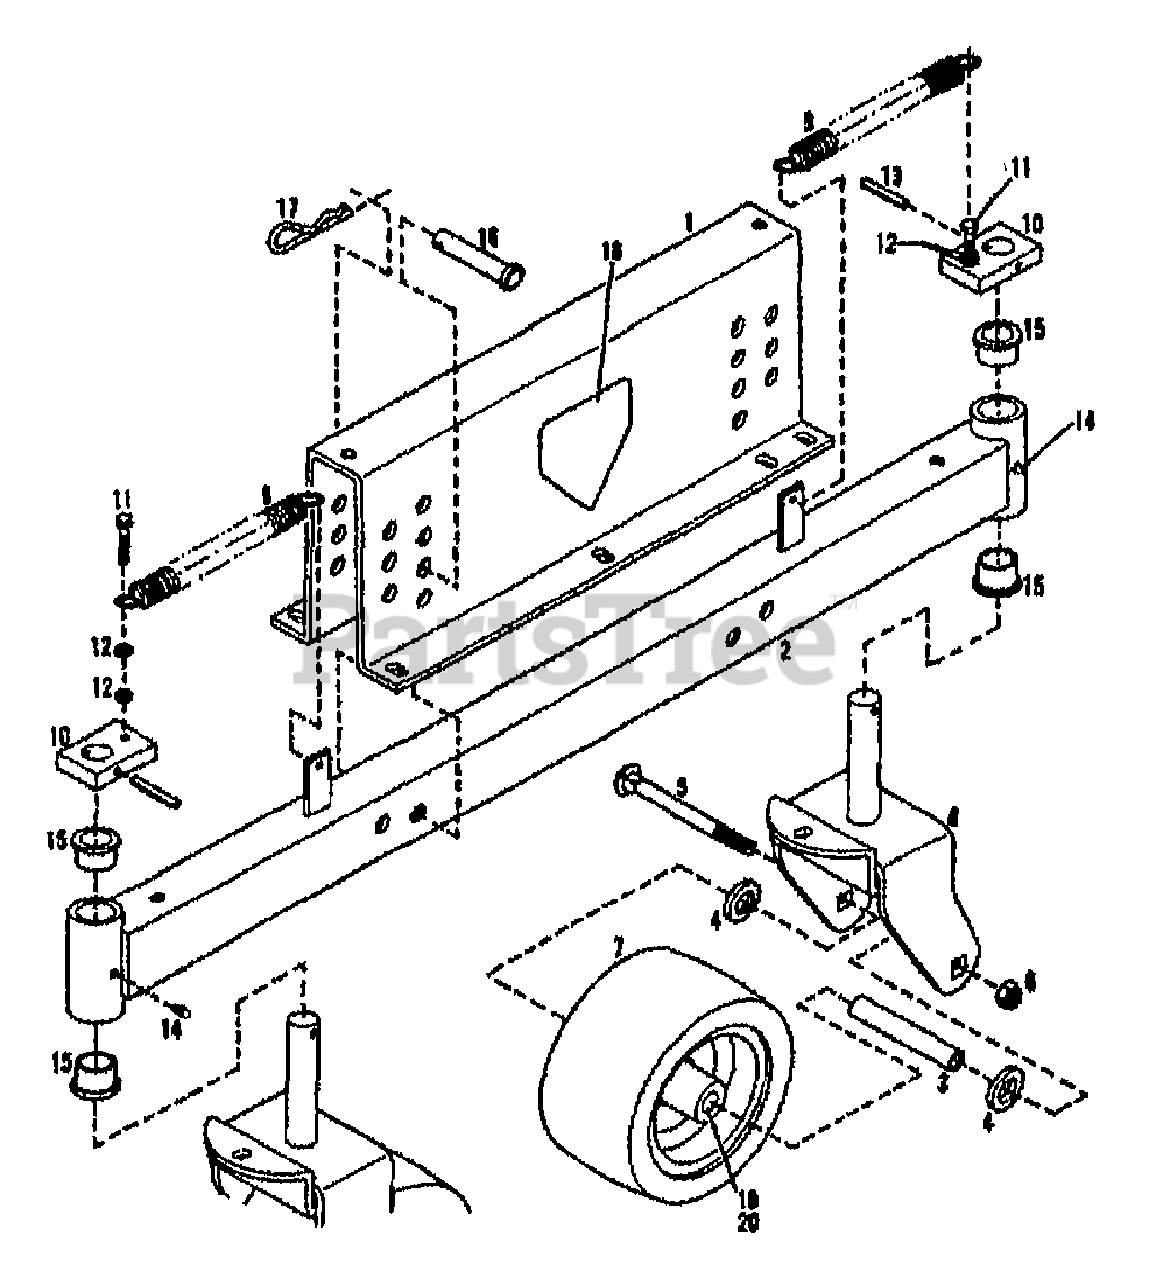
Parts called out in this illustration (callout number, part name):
1	MOUNT-GAGE WHEEL W/DECALS
3	SLEEVE-WHEEL
4	WASHER-1.5X.812X.134 ZP
5	ASSM-WHEEL SUPPORT
5	SCR-CARR 1/2-13X4.75
6	NUT-TOP LOCK 1/2-13 ZP
7	ASSM-TIRE&WHEEL 6.25X3.
8	ASSM-WHEEL YOKE
14	FITTING-GREASE 1/4-28X2.00
15	BEARING-FLANGE
16	PIN-CLEVIS .62X2.50 ZP
17	PIN-HITCH .149DIA
18	DECAL-OPEI CAUTION
19	BEARING-ROLLER
20	CAP-BEARING
128	RING-HEAVY EXT HD 1.0 ID
129	WASHER-THRUST
